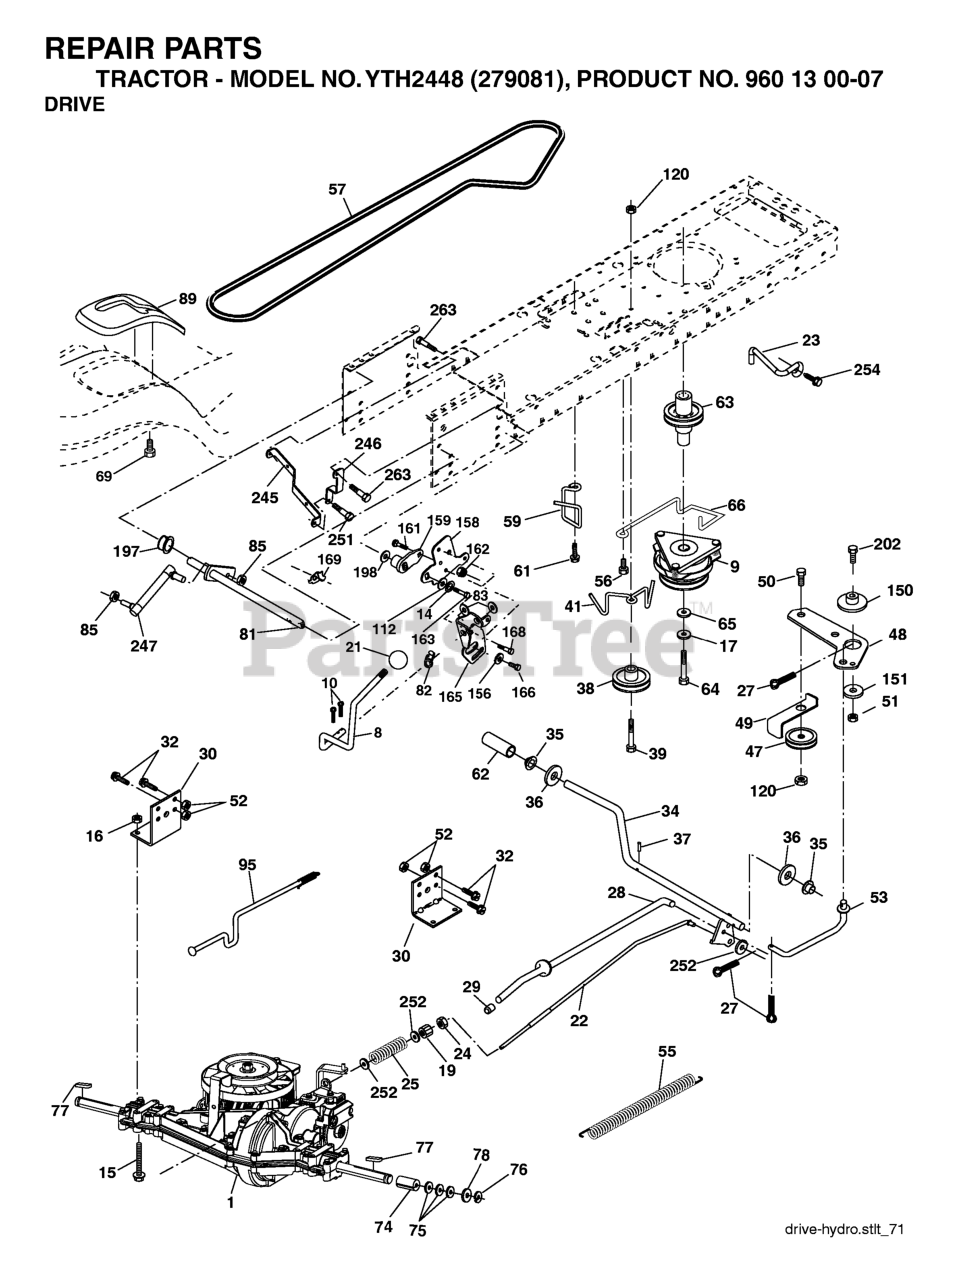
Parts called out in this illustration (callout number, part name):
8	ROD.SHIFT.FENDER.ADJ.STLT
9	CLUTCH ELECTRIC
10	PIN COTTER
14	LOCKWASHER
15	BOLT HEX 5/16-18 GR 5
16	NUT.71038.31-18.HEX.NYLOCK
19	NUT
21	KNOB.DELUXE.(PISTOL.GRIP).BLAC
23	BRACKET, ANTI-ROTATION
24	NUT
25	SPRING ROD LT
27	COTTER PIN
28	ROD, PARKING BRAKE
29	PLUNGER CAP
30	BRKT, TRNSXLE MNT 20"
32	BOLT
34	SHAFT, FOOT PEDAL
35	BEARING.NYLON
37	DRIVE PIN
38	PULLEY IDLER COMPOSITE
41	KEEPER, BELT IDLER
47	IDLER PULLEY
48	BELLCRANK, CLUTCH
49	RETAIN BELT
50	BOLT.3/8-16X1.50
52	LOCKNUT
53	LINK, CLUTCH LT
55	SPRING, RETURN LT
56	SCREW.3/8-16
59	KEEPER, BELT CENTER
61	SCREW 3/8-16X.875
62	PEDAL COVER T
63	PULLEY- ENGINE
64	BOLT HEX 7/16-20X4-1/4"
65	LOCKWASHER
66	KEEPER BELT ENGINE
69	SCREW.HI-LO.CONSOLE
74	SPACER AXLE
77	SQUARE KEY
82	SHIFT SPRING
83	WASHER
85	NUT LOCK CENTER 1/4 -28 FNTHD
89	CONSOLE, SHIFT, STL, AUTO GREY
120	NUT LOCK FLG 3/8-16 UNC
150	SPACER, RETAINER
151	WASHER 12/32X2X10GA
156	WASHER.SRRTD.5/16
158	BRACKET
159	RB HUB.SHIFT
161	BOLT
162	NUT.CROWNLOCK.1/4
165	RP BRACKET
166	CAPSCREW.HXHD.FLG.5/16-18X.625
168	BOLT.SHOULDER.5/16-18X
169	PLATE.FASTENING.CROSS.SHAFT
197	NYLINER SNAP 5/8" ID
198	WASHER.NYL.7/8IDX.105"HYD CR
251	SCREW 5/16-18X1
252	WASHER
254	SCREW 3/8-16X1
263	SCREW, 3/8-16X3/4
